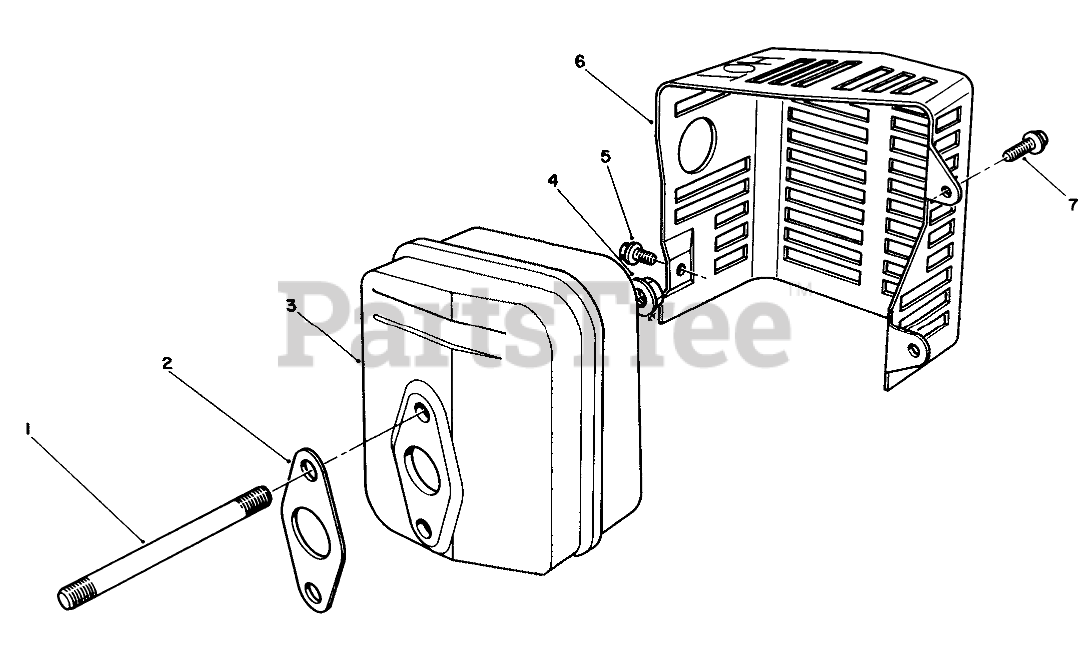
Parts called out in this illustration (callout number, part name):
1	Stud-Muffler
2	GASKET
3	MUFFLER
5	SCREW
6	COVER
